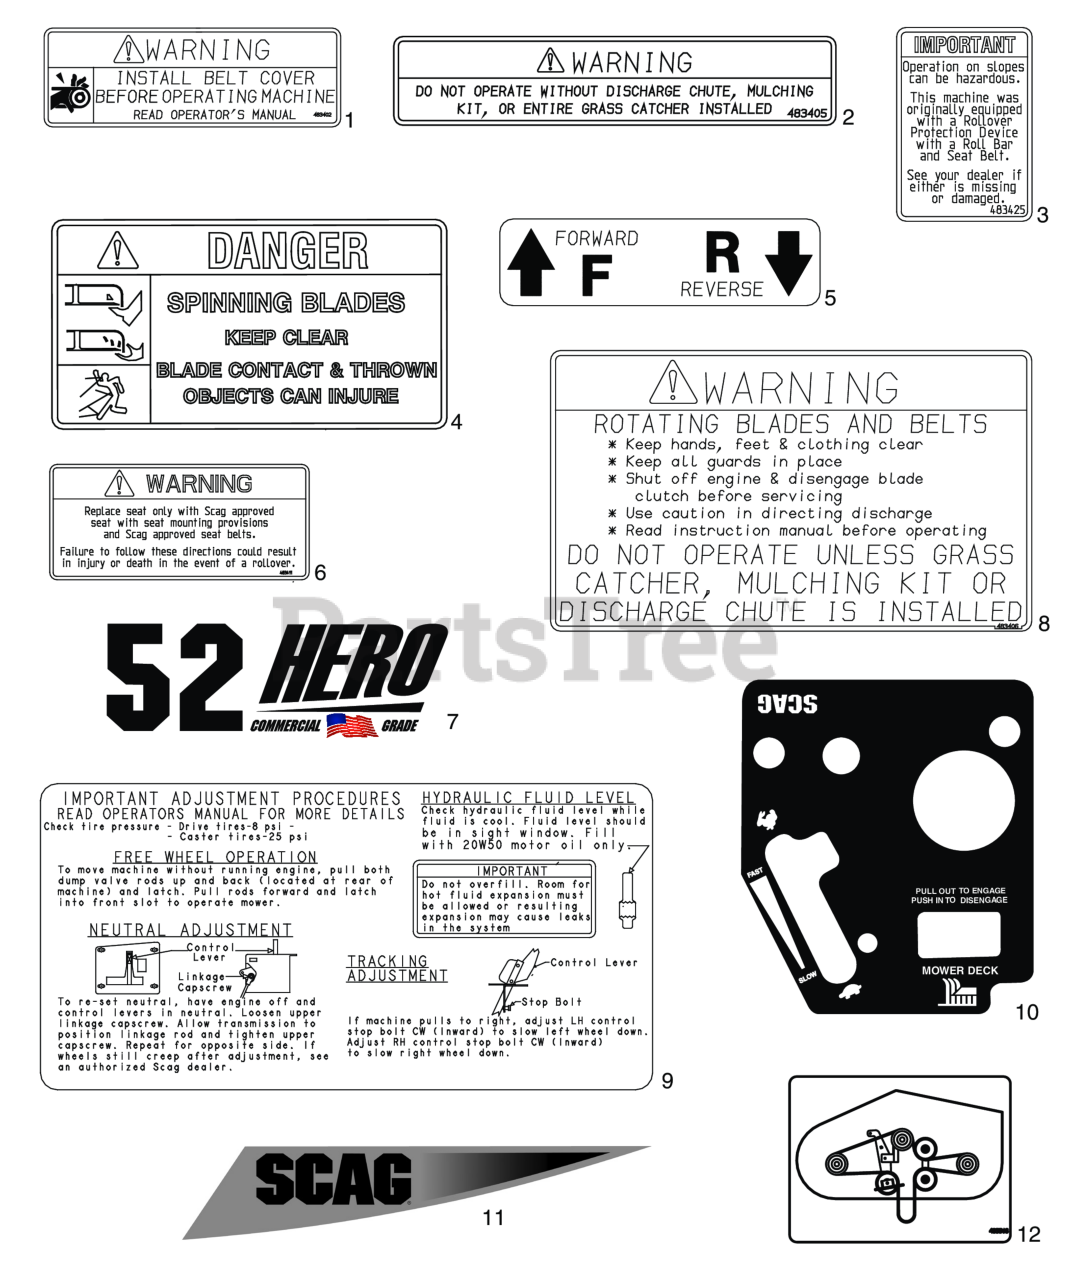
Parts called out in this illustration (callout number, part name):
1	Decal, Warning - Belt Cover
2	Decal, Warning-Discharge
3	Decal, ROPS
4	Decal, Spinning Blades
5	Decal, Traction Control
6	Decal, Seat Replacement
7	Decal, 48H Commercial
8	Decal, Warning - Rotating Blades
9	Decal, Adjustment SFZ
10	Decal, Instrument Panel - SFZ48, SFZ52 & SFZ 61
11	Decal, Scag RH Fuel Tank
12	Decal, SZL / SFZ / SPZ Belt Routing
